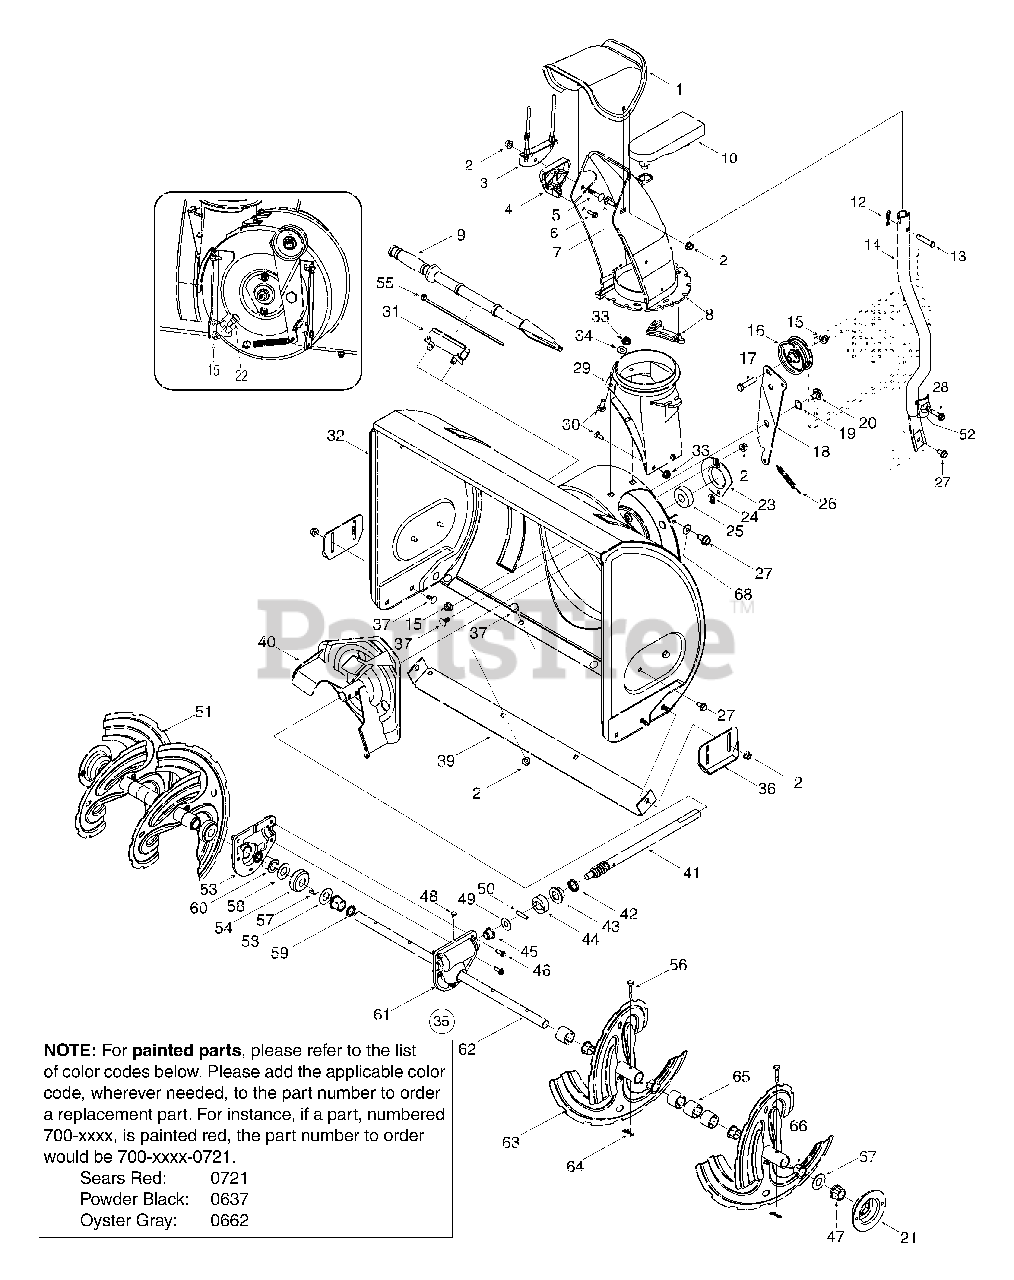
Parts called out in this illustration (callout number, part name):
1	Upper Chute
2	Flange Lock Nut, 5/16-18
4	Chute Tilt Cable Guide
5	Carriage Bolt, 5/16-18 x 1.50
6	Hi-Lo Screw, 1/4-15 x 0.75
7	Carriage Bolt, 5/16-18 x 1.0
8	Lower Chute Assembly, with flange keepers
8	Chute, Keeper Flange
9	Clean-Out Tool
10	4-Way Chute Control(TM) Assembly
12	Cotter Pin
13	Clevis Pin
16	Flat Idler Pulley
17	Hex Bolt, 3/8-16 x 1.75
19	Wave Washer
20	Shoulder Screw
22	Shoulder Screw
23	Bearing Housing
24	Push Nut
25	Ball Bearing
26	Extension Spring
27	AB Screw, 5/16-12 x 0.75
28	TT Screw, 5/16-18 x 1.750
29	Chute Adapter
30	Carriage Screw, 1/4-20 x 0.75
31	Clean-out Tool Mtg. Bracket
33	Flange Lock Nut, 1/4-20
34	Flat Washer
35	Gearbox Assembly Complete
37	Carriage Bolt
41	Worm Shaft
42	Oil Seal
43	Flange Bearing
44	Thrust Collar
45	Flange Bearing
46	TT Screw, 1/4-20 x 0.75
47	Hex Flange Bearing
49	Flat Washer
50	Dowel Pin
52	Handle Tab
53	Reducer Hsg.-RH (Incl Ref. 59-60)
54	Worm Gear, 20T
55	Cable Tie
56	Shear Pin
57	Key
58	Flat Washer
59	Oil Seal
60	Flange Bearing
61	Reducer Hsg.-LH (Incl Ref. 59-60)
62	Auger Axle
64	Bow Tie Cotter Pin
65	Spacer
66	Flange Bushing
67	Flat Washer
68	Bell Washer
